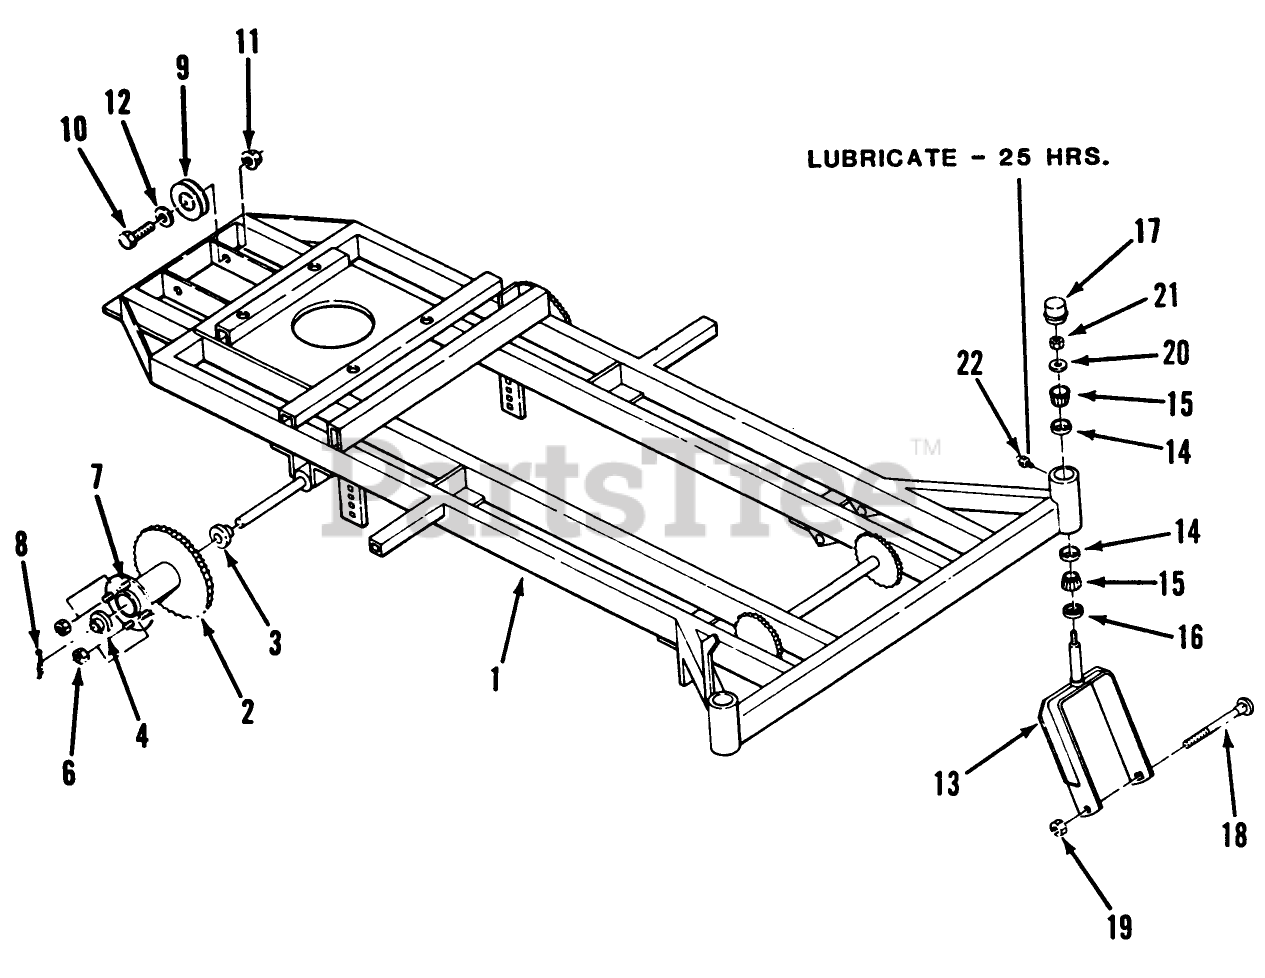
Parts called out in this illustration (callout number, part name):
8	Roll Pin
9	PULLEY-IDLER
11	NUT
13	Front Wheel Forks
